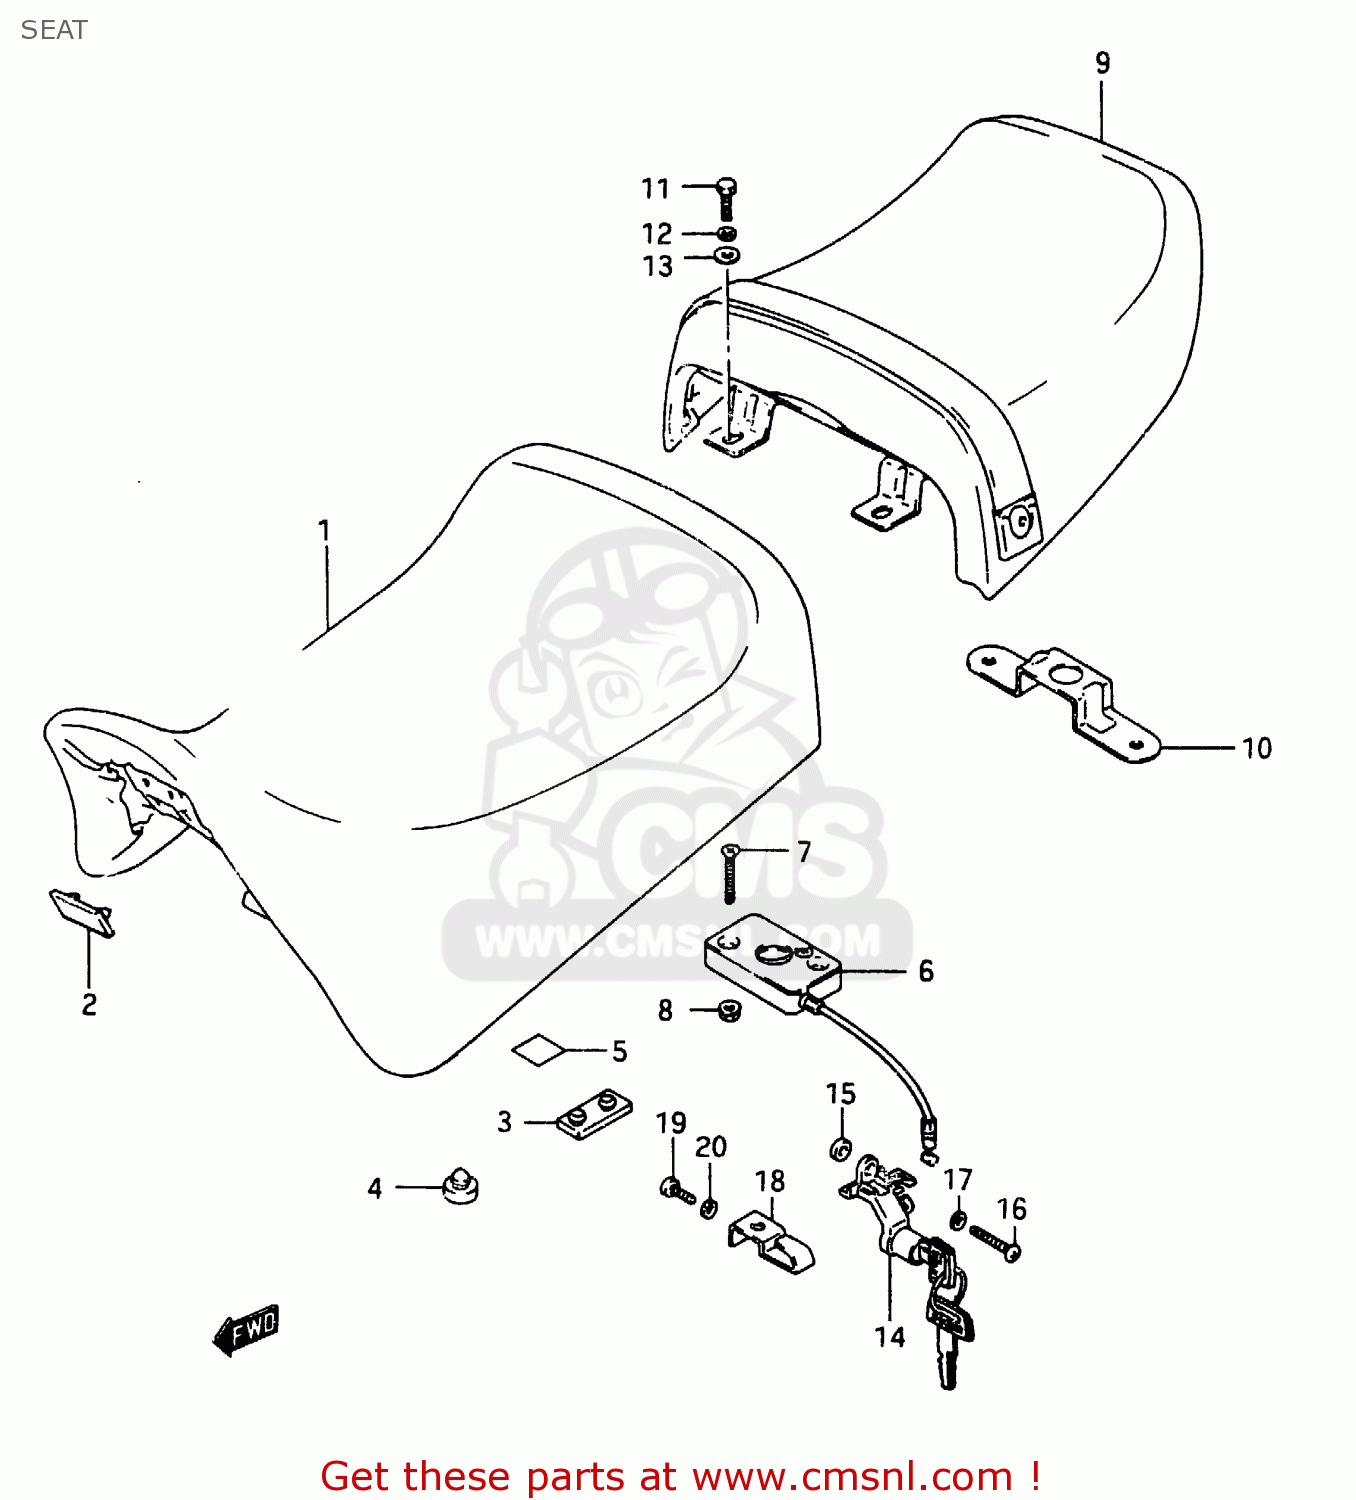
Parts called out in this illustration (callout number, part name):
1	SEAT ASSY (RED)
2	CUSHION
3	CUSHION
4	CUSHION(11.5X22X20)
5	TAPE
6	BRACKET, SEAT SUPPORT REAR
7	SCREW
8	NUT
9	SEAT ASSY, PILLION (RED)
10	PLATE,PILLION HOOK RR
11	BOLT
12	WASHER,LOCK
13	WASHER(6.5X16X1.2)
14	LOCK ASSY, SEAT
15	SPACER(6.5X12X3.2)
16	SCREW
17	WASHER,LOCK
18	HOLDER, HELMET
19	SCREW
20	WASHER,LOCK
